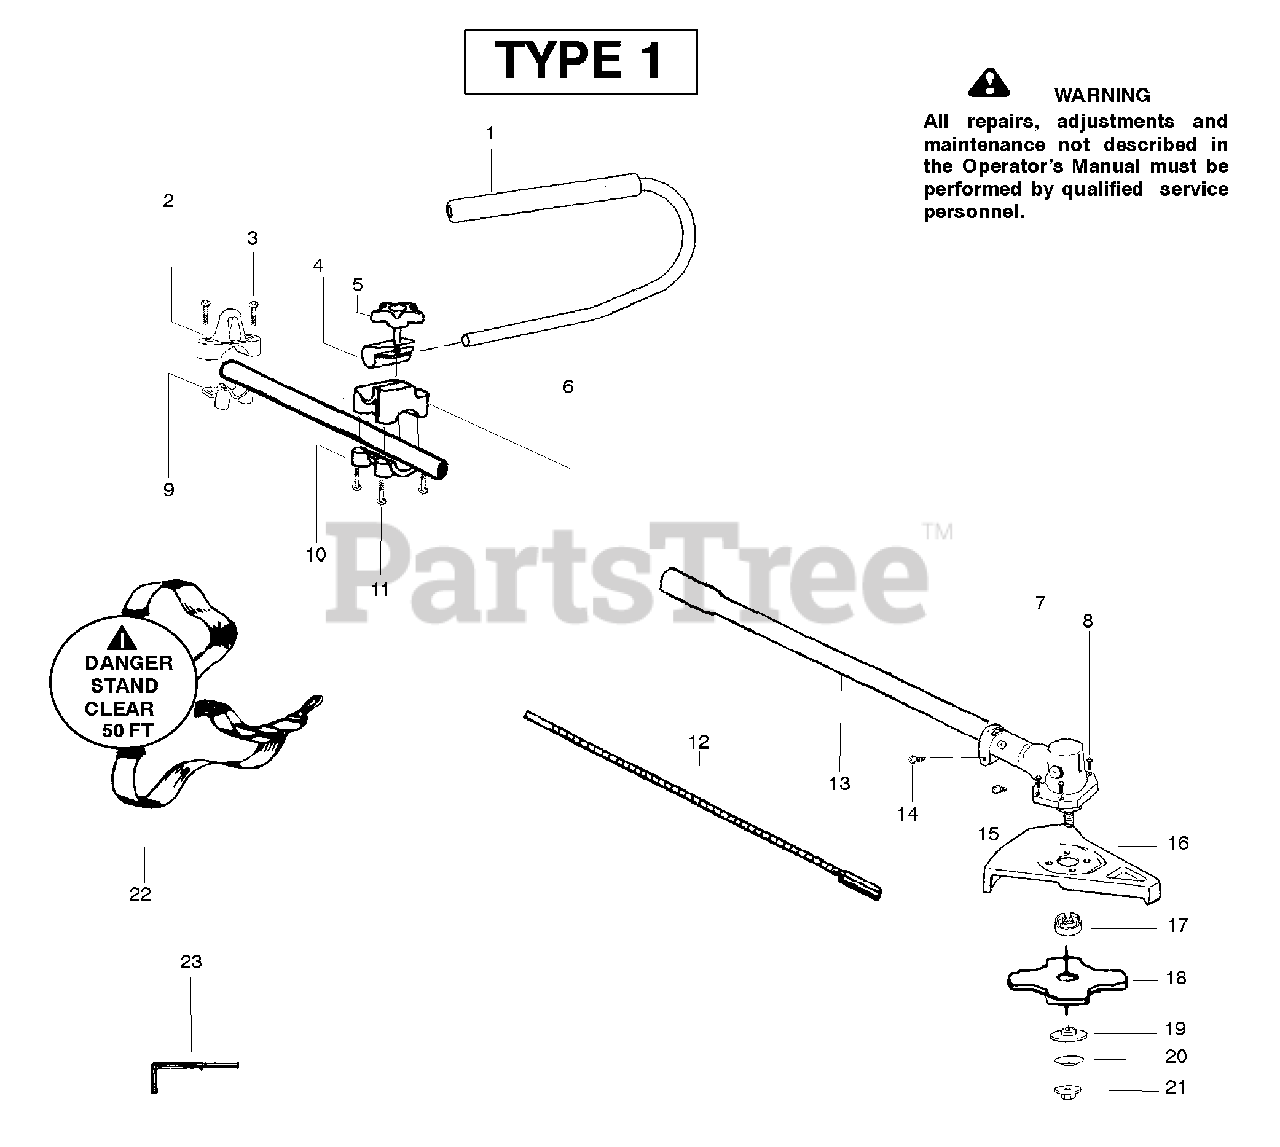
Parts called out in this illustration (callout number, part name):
1	Kit-Handlebar
2	Clamp-Harness Upper
4	Clamp-Handlebar
5	Knob
6	Base-Clamp
7	Assy-Gearbox
9	Clamp-Harness Lower
10	Kit-Clamp-Tube
12	Flexshaft-Split boom
13	Assy.-Driveshaft
15	Screw-Alignment
16	Kit-Blade Shield
17	Dust cup - Blade
18	Accy.-Weed Blade (8")
19	Washer-Blade Retaining
20	Washer-Belleville
21	Nut-Flange
22	Assy-Shoulder Strap
23	Wrench-Hex (5/32")
